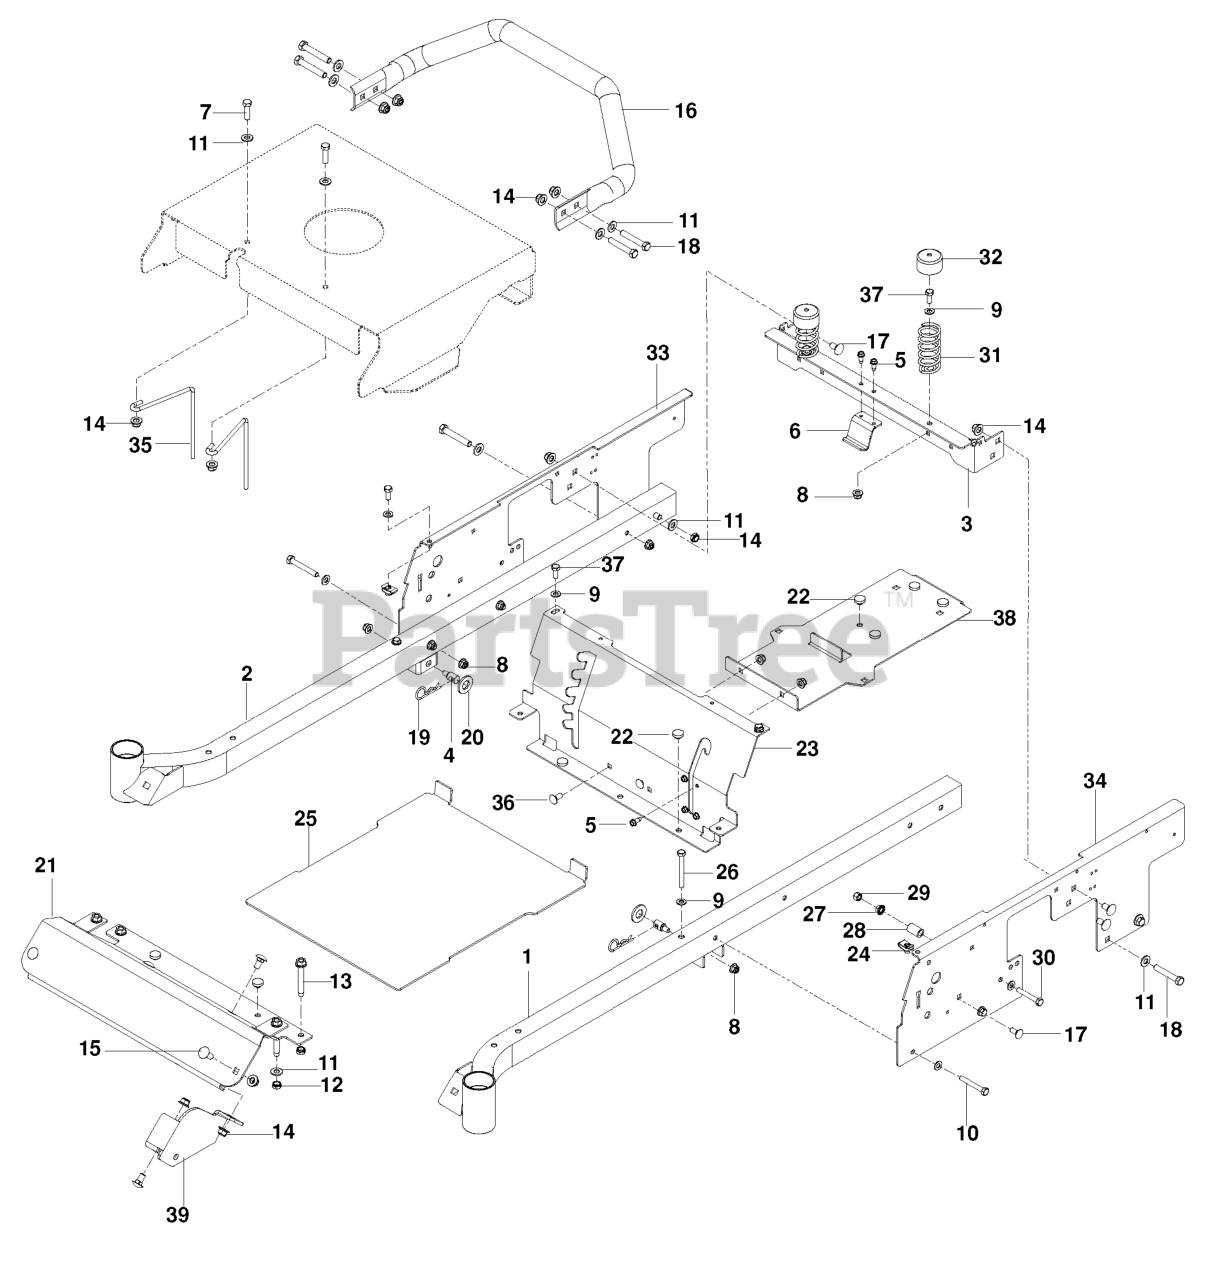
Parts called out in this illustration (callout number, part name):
1	FRAME TUBE, LH, ORG
2	FRAME TUBE, RH, ORG
3	SEAT SUPPORT, REAR ORG
4	STUD.FASTNER.W/ANTI-ROTATE
5	SCREW 1/4 X 5/8
6	HOLDING DEVICE, FUEL TANK, BLK
7	HCS 3/8C X 1 1/4 GR5
8	5/16-18 NYLOC FLANGE NUT
9	FLAT WASHER 5/16 SAE
11	WASHER 3/8 SAE FLAT
12	NUT HEX 3/8-16 NYLON, THIN
13	ENGINE BOLT, SPECIAL
14	NUT 3/8-16 HEX FLG NYLOC ZD
15	RHSNB 3/8C X 1
16	IMPACT BAR, ORG
17	RHSNB 3/8-16 X 3/4 GR5 ZD
18	HCS 3/8C X 2 1/4
19	HAIRPIN #4
20	WASHER 5/8 FLAT
21	FOOT REST, ORG
22	GROMMET, BUMPER
23	PANEL.SEAT.SUPPORT.ORANGE
24	U-CLIP 5/16-18 NUT RETAINER
25	FOOT PLATE, ORG
26	HCS 5/16C X 2-3/4
27	NUT 5/16C WHIZ
29	NUT 5/16 NYLOC
30	HCS 5/16-18X2
31	SEAT SPRING
32	SPRING CAP
33	PLATE, RT SIDE, ORG
34	PLATE, LT SIDE, ORG
35	BELT GUIDE
36	BOLT 5/16C X 3/4" CARRIAGE
37	HCS 5/16C X 3/4
38	SUPPORT, TANK/BATT, BLK
39	BRACKET, FRONT DECK, BLK
